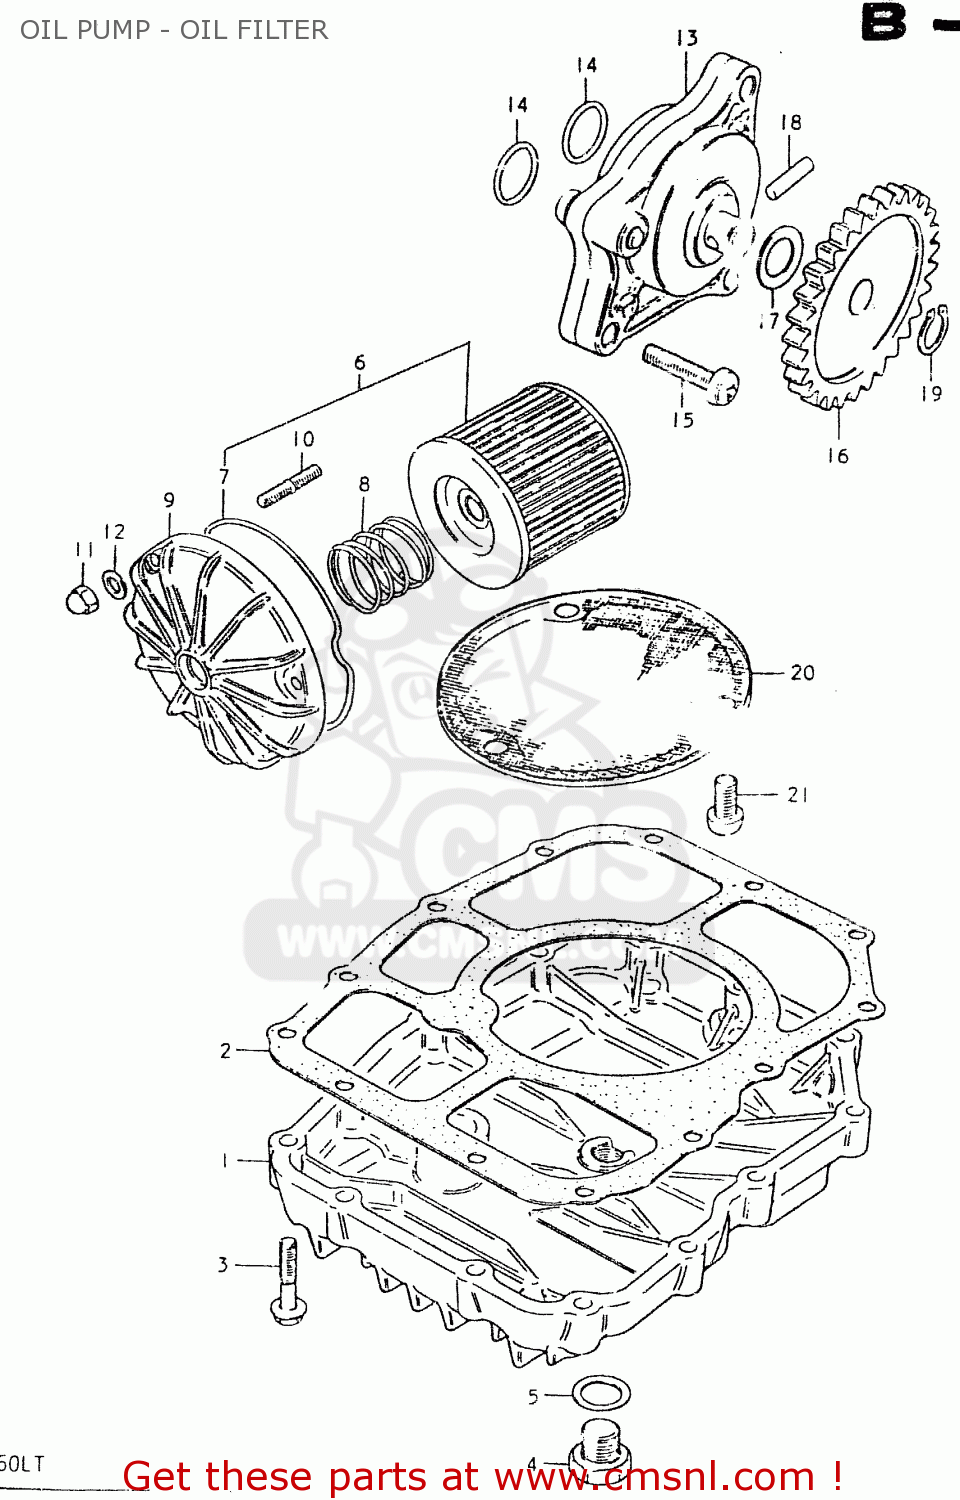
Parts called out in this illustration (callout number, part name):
1	PAN,OIL
2	GASKET,OIL PAN (MCA)
3	BOLT
4	PLUG
5	GASKET(14X19.2X2) (NAS)
6	ENGINE OIL FILTER SET
7	O RING,OIL FILTER CHAMBER CAP
8	SPRING
9	CAP,OIL FILTER
10	STUD 6X20
11	NUT
12	WASHER
13	PUMP ASSEMBLY,OIL
14	O RING(D:1.9,ID:13)
15	SCREW
16	GEAR,OIL PUMP DRIVEN
17	SHIM
18	PIN(4X15.8)
19	CIRCLIP
20	STRAINER,ENGINE OIL
21	SCREW 6X12
